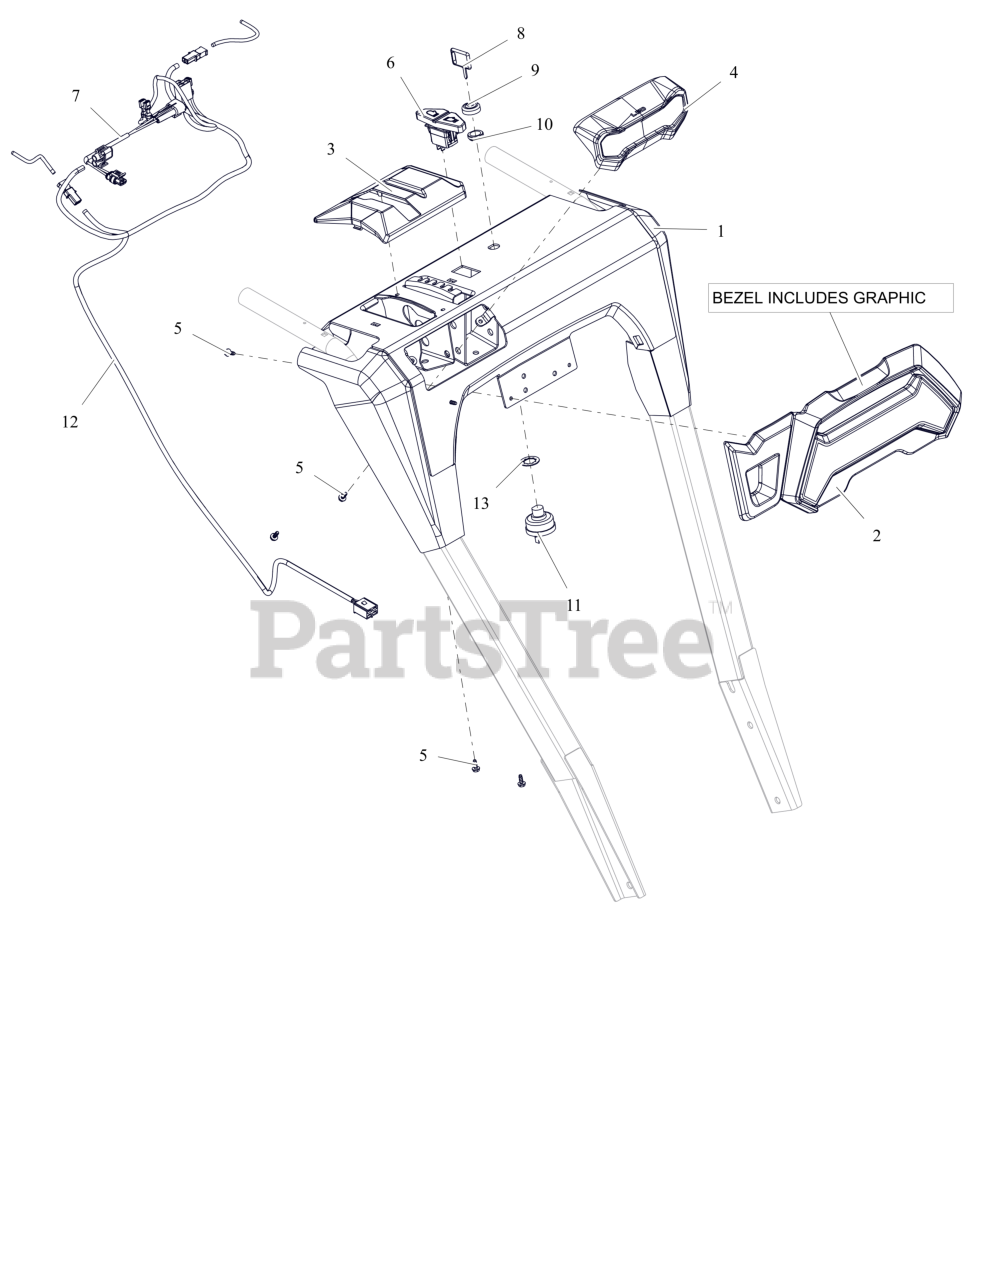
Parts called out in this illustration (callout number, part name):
1	PANEL, DASH-12V PB W/DECAL
2	BEZEL- LARGE - POWER BRUSH
3	BEZEL, SHIFT HYDRO PIVOT DECAL
4	HEADLIGHT ASM- LED
5	SCR, PLASTIC #10X.50
6	SWITCH- ROCKER SPST-ON/OFF
7	HARNESS- WIRE - LED LT JUMPER
8	KEY -W/CAP
9	CAP - IGNITION SWITCH
10	NUT-PANEL .625-32 GRECO
11	IGNITION SWITCH ASSEMBLY
12	HARNESS,ELEC - HANDLEBAR 12V
13	WSHR-LK-INT .625X.045 YWZC
